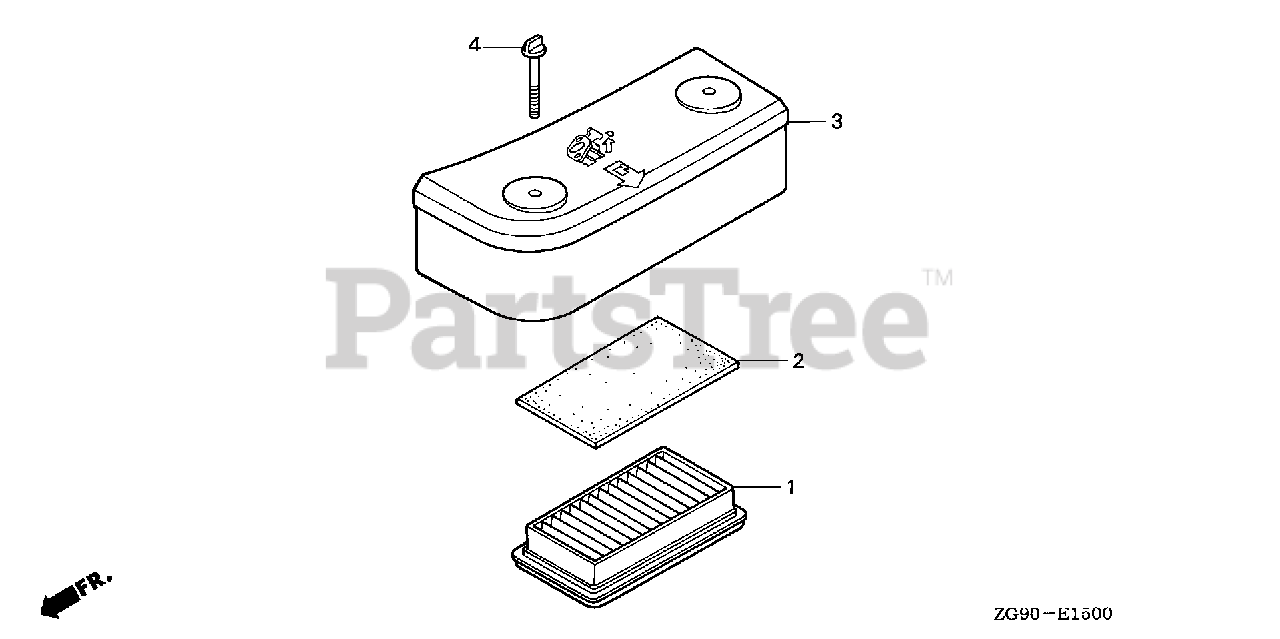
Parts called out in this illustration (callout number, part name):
1	ELEMENT, AIR CLEANER
2	FILTER (OUTER)
3	COVER, AIR CLEANER *NH1* (BLACK)
4	BOLT, AIR CLEANER (6MM)
